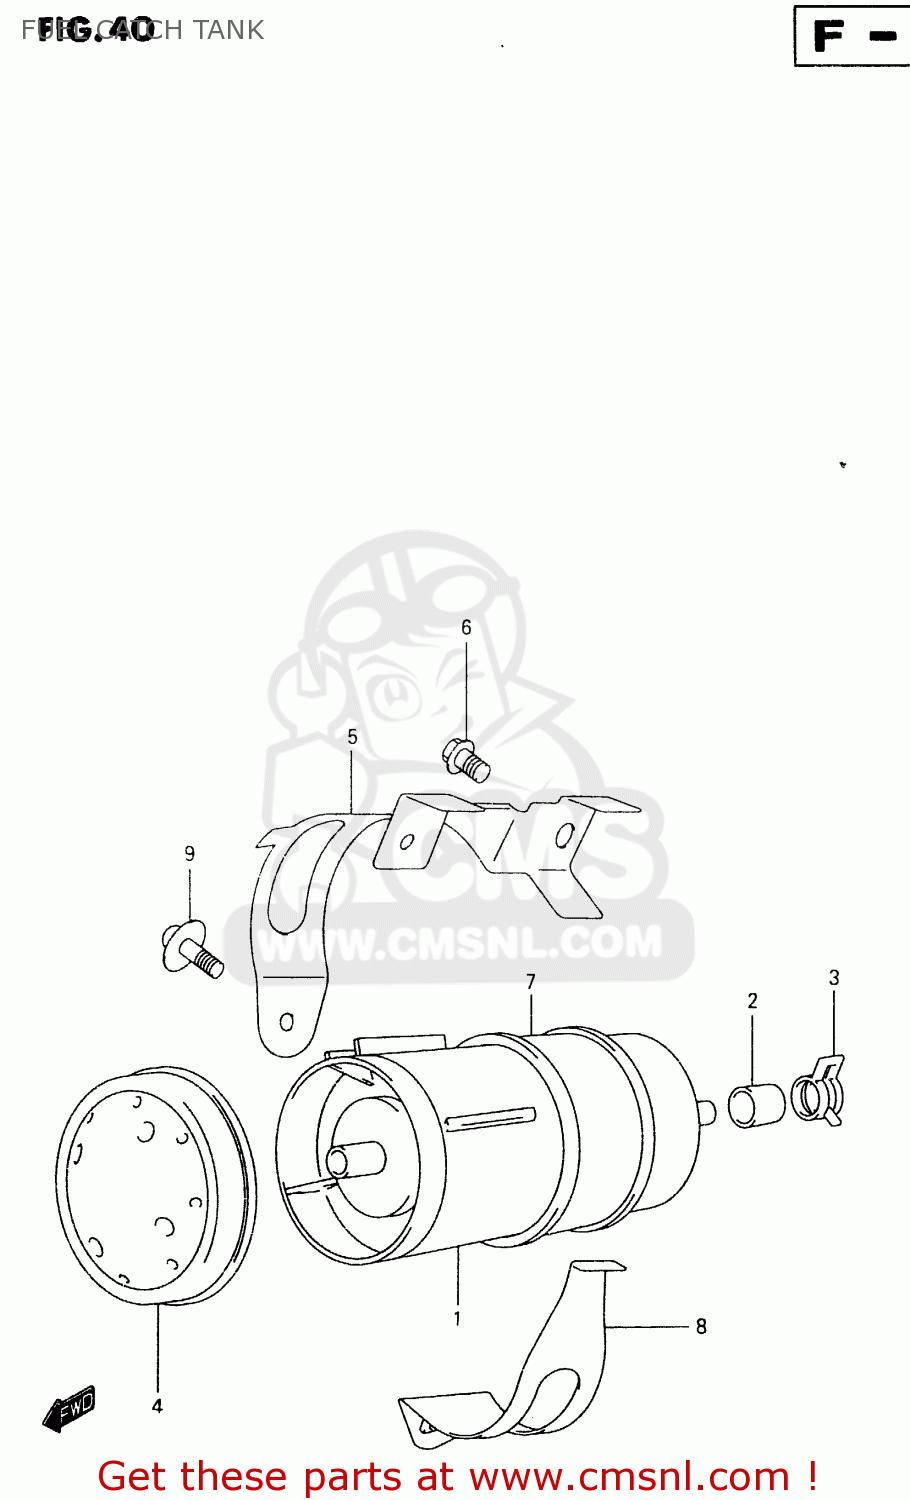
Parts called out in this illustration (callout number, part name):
1	TANK,FUEL CATCH
2	CAP,OD:11.5
3	CLIP
4	CAP,CANISTER
5	BRACKET,CATCH TANK
6	BOLT(6X16)
7	CUSHION,CANISTER
8	HOLDER,CATCH TANK
9	SCREW 6X12
